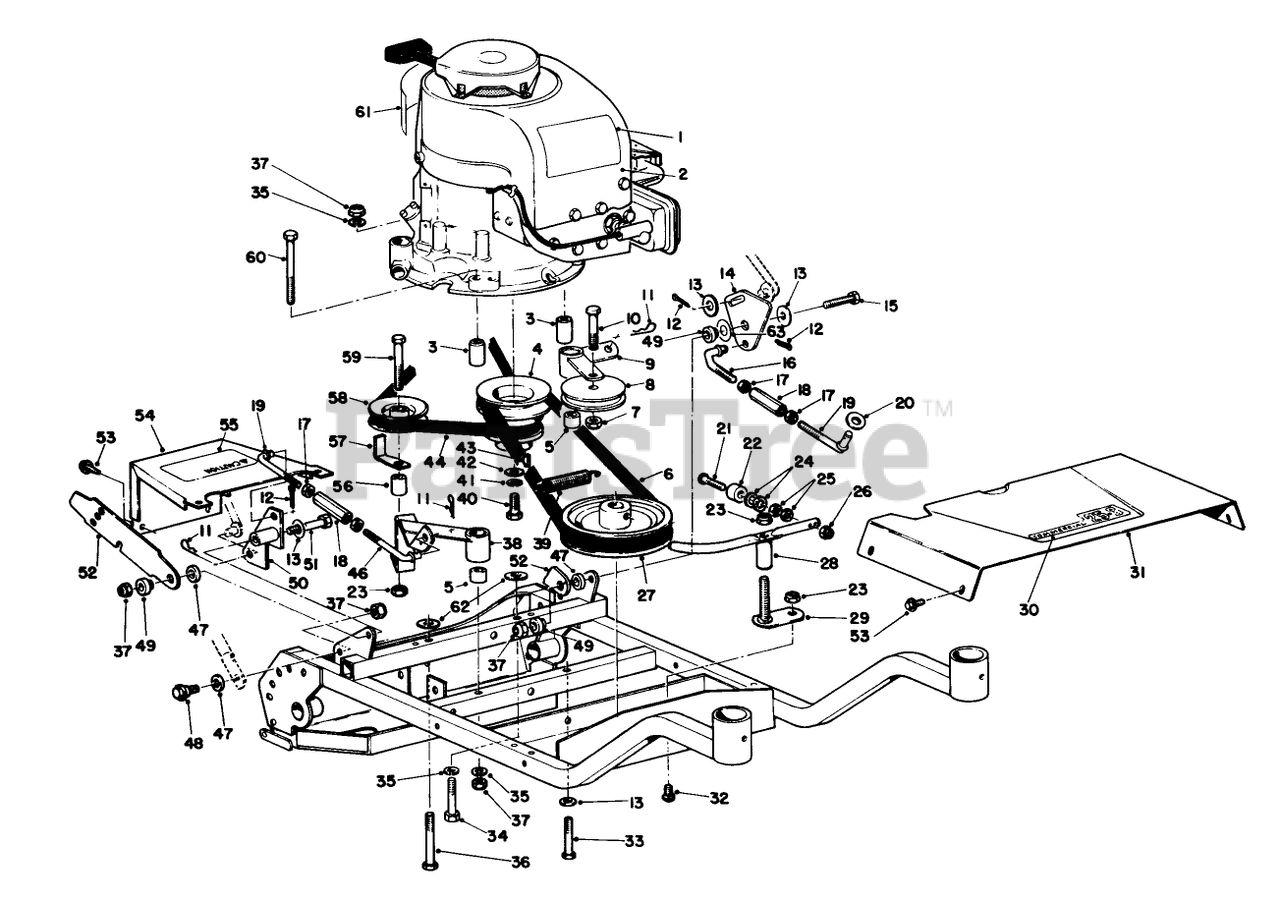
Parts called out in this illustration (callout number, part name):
1	Decal
2	Engine
3	ENGINE PIVOT SPACER
4	ENGINE PULLEY RO
5	BUSHING
7	Nut
8	PULLEY B
9	Arm and Bushing (Incl. Ref. #5)
10	Screw
11	PIN-COTTER
12	PIN-COTTER
13	WASHER-PLAIN
14	CUTTR BELLCRANK WA R
15	5/16-18 X 1-3/4 SCREW
16	CUTTER LINK
17	NUT-KEPS
18	CONTROL ROD SLEEVE
19	LINK CONTROL ROD
20	WASHER
21	10-24X1-1/2 RND HD MS
22	BUMPER
23	NUT-HEX
24	WASHER-FLAT
25	NUT-HEX
26	NUT-LOCK, NI
27	DECK PULLEY R
28	Brake Arm
29	Base Pivot
30	DECAL
31	FRONT SHROUD R
32	SCREW-CARR
33	SCREW-HH
34	SCREW-HH
35	WASHER-LOCK/SP
36	SCREW-HH
37	Nut
38	Arm and Bushing (Incl. Ref #5)
39	EXTENSION SPRING
40	SCREW-HH
41	WASHER-LOCK
42	WASHER-FLAT
43	KEY-WOODRUFF
44	V-BELT
46	Control Rod
47	SPACER
48	SCREW-SHOULDER
49	PIVOT
50	TRACT BELLCRANK WA R
51	SCREW-HH
52	HANDLE LATCH
53	Hex Head Capscrew
54	Rear Shroud
55	DECAL SAF INST
56	SPACER
58	IDLER PULLEY R
59	SCREW-HH
60	SCREW-HH
61	Decal
62	WASHER
63	WASHER
